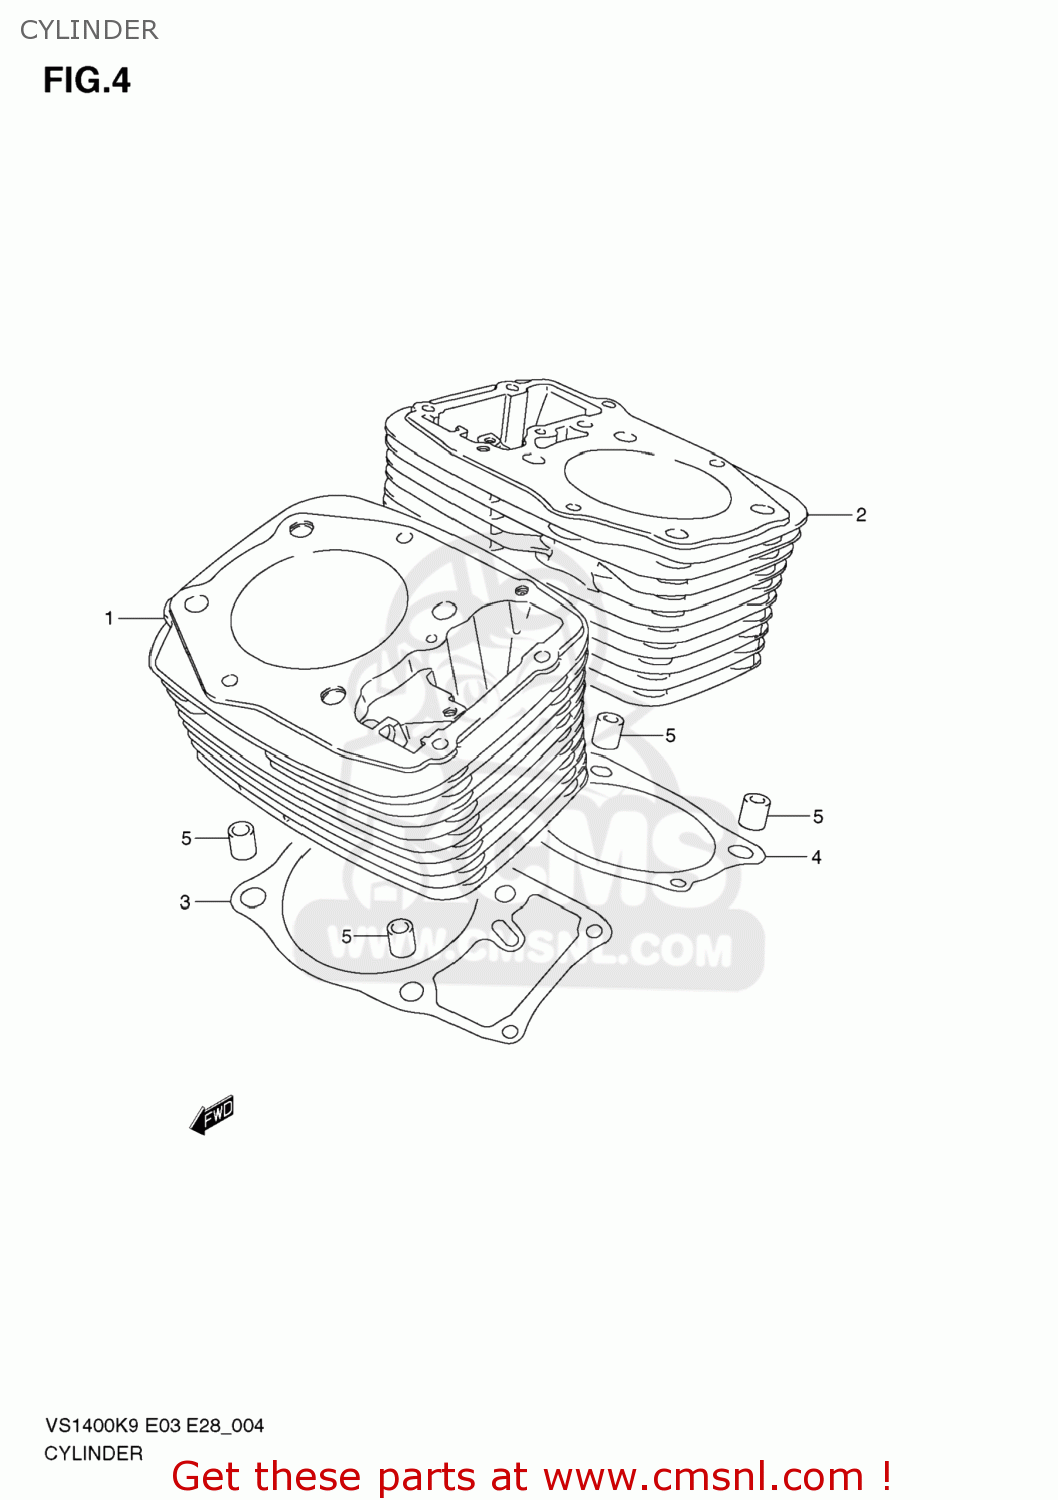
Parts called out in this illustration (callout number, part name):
1	CYLINDER,FR
2	CYLINDER,RR
3	GASKET,CYLINDER FR (NAS)
4	GASKET,CYLINDER RR (NAS)
5	PIN
